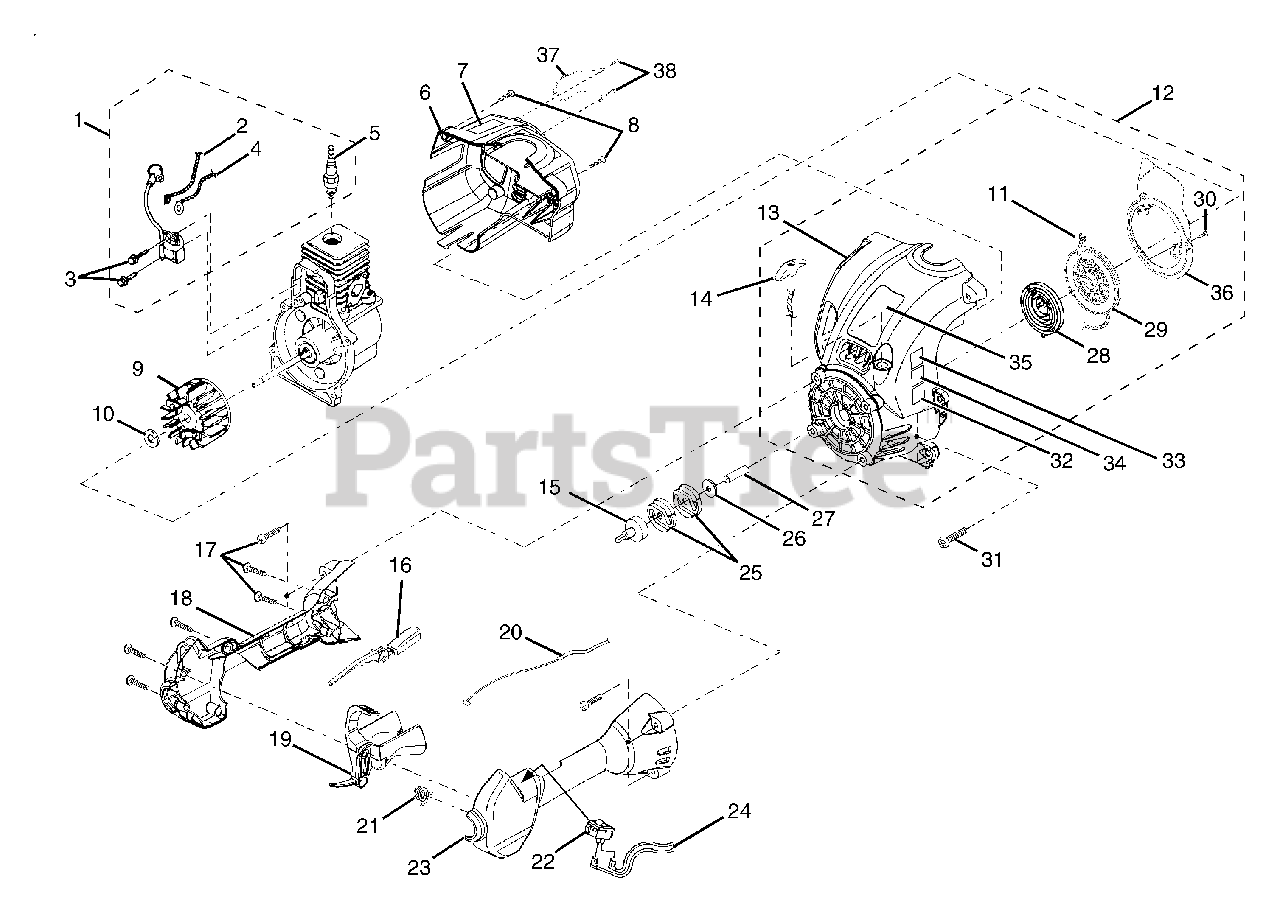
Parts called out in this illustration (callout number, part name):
1	IGNITION KIT
2	ELECTRICAL LEAD
4	ELECTRICAL LEAD
5	SPARK PLUG
6	REAR COVER
7	LOGO PLATE
8	SCREW (10 - 14 x 7/8)
9	ROTOR AND PAWL ASSEMBLY
11	STARTER ROPE 42 in.
12	STARTER ASSEMBLY
13	STARTER HOUSING AND EYELET
14	ERGO GRIP
15	DRUM AND CONNECTOR
16	INTERLOCK TRIGGER
18	CONTROL HANDLE / RH
20	THROTTLE CABLE
22	SWITCH
23	CONTROL HANDLE / LH
24	ELECTRICAL LEADS
25	CLUTCH DISK (ST185 & ST385)
26	WASHER
28	SPRING & CONTAINER
29	STARTER PULLEY
32	DECAL, 112 POWER SOUND
33	DECAL, ZIP START
34	DECAL, CE
35	DECAL, MODEL
36	AIR BAFFLE PLATE
37	MUFFLER GUARD
